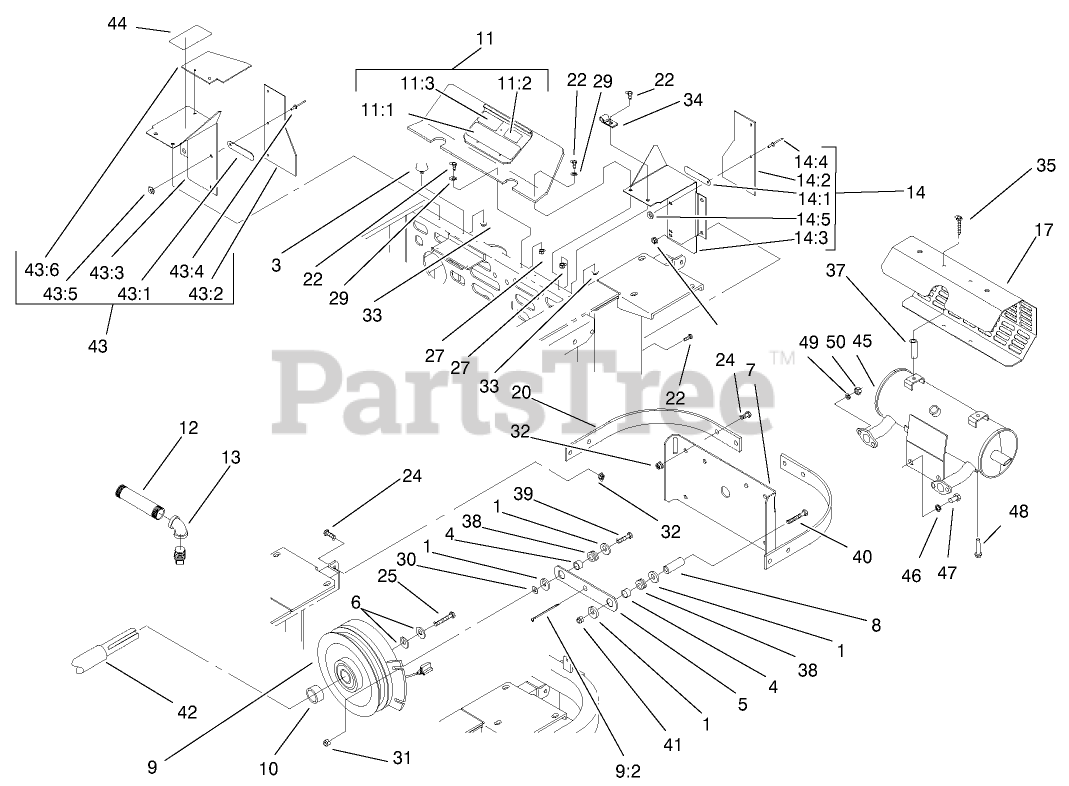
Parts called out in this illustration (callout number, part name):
1	Washer
3	Bumper
4	Spacer
5	Strap
6	Disc-Spring
7	Guard
8	Spacer
9	Clutch
9:2	Tie-Plastic
10	Spacer
11	Shield ASM
11:1	Decal-Belt, Drive
11:2	Decal-Guard
11:3	Decal-Important
12	Nipple
13	Elbow
14	Shield-LH
14:1	Clip
14:2	Shield-Engine
14:3	Baffle-Engine Shield, LH
14:4	Pop Rivet
14:5	WASHER-PLAIN
17	Guard-Muffler
20	Bracket-Guard, Top
22	SCREW-HH
24	SCREW-HH
25	SCREW-HH
27	NUT-LOCK
29	WASHER-FLAT
30	WASHER-FLAT
31	NUT-HF
32	NUT-HHF, WHIZ
33	NUT-HF
34	Clip
35	Screw-HWH
37	Spacer
38	Grommet
39	SCREW-HH
40	SCREW-HH
41	NUT-LOCK, NI
43	Shield ASM, RH
43:1	Clip
43:2	Shield-Engine
43:3	Shield-RH
43:4	Pop Rivet
43:5	WASHER-PLAIN
43:6	Baffle, Engine Cooler
44	Decal-Belt Routing
45	Muffler-26hp Kohler
46	WASHER-LOCK
47	SCREW-HH
48	Screw-HWH
49	WASHER-LOCK
50	NUT-HEX
